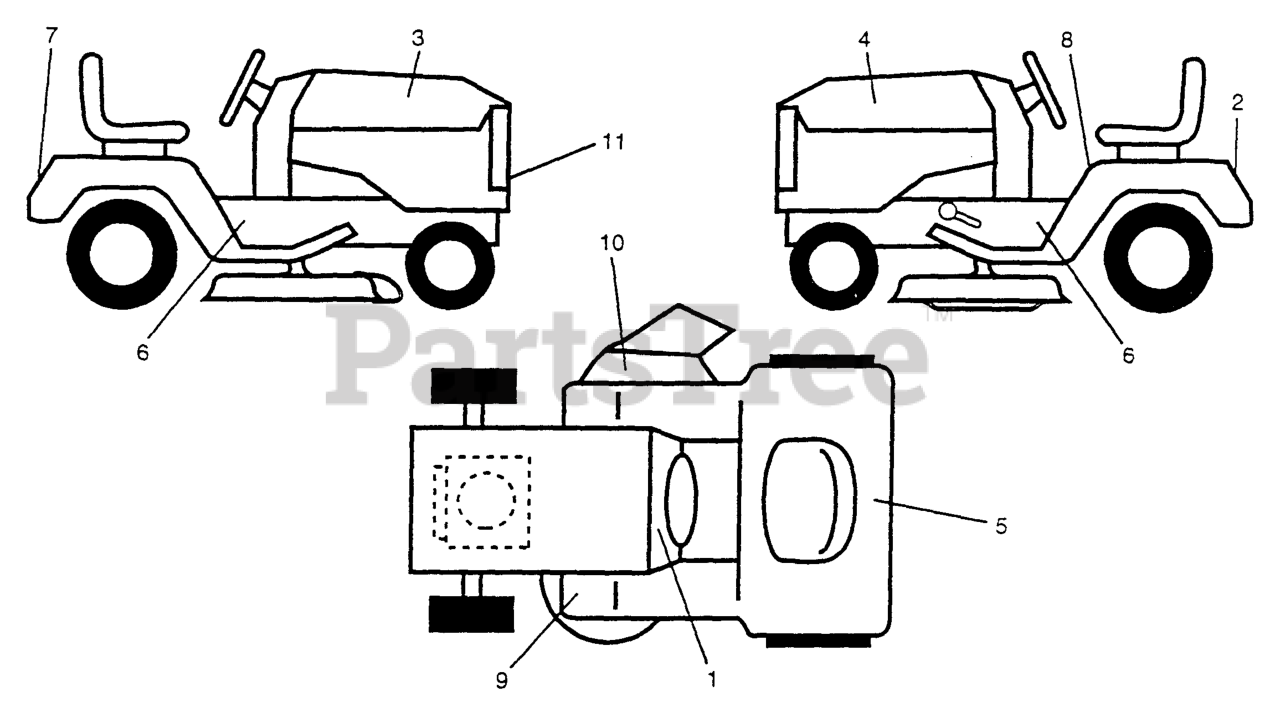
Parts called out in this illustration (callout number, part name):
1	DECAL
2	DECAL, USA
3	DECAL HOOD RH NLA
4	DECAL HOOD LH NLA
6	DECAL, CHASSIS
7	DECAL FENDER NLA
8	DECAL CAUTION
10	DECAL WARNING (ENGLISH/FRENCH)
11	DECAL GRILL HUSQ NLA
